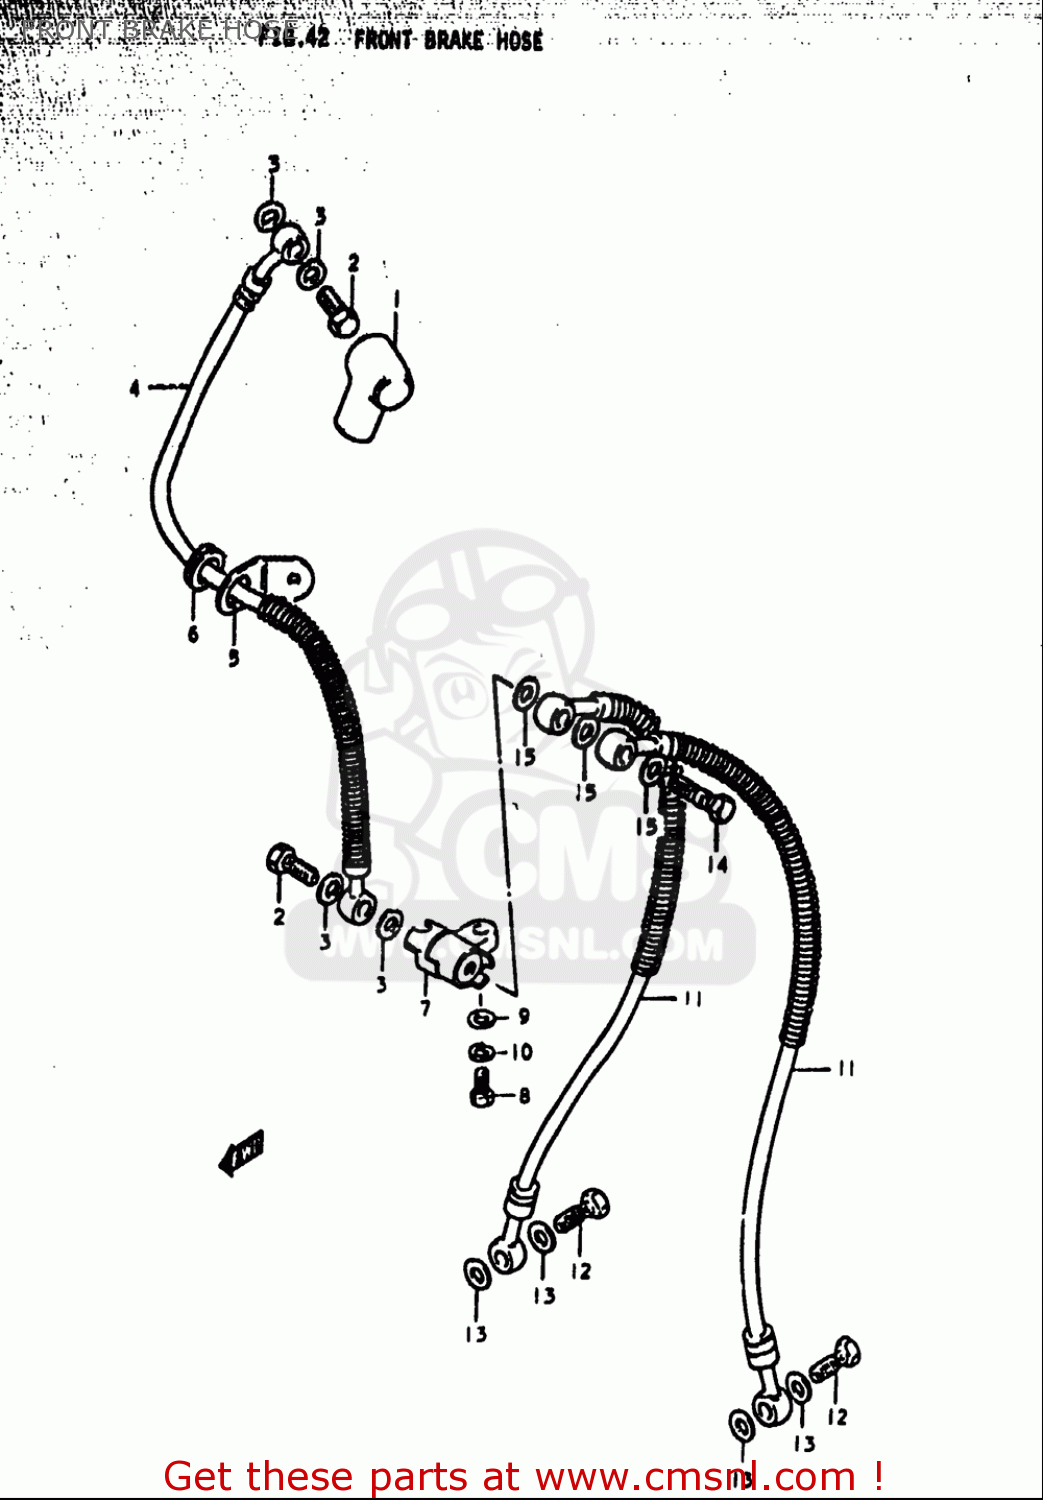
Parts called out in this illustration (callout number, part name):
2	BOLT UNION
3	WASHER(10X15X1.5)
5	GUIDE,BRAKE HOSE
6	GROMMET
7	JOINT,BRAKE HOSE
8	BOLT
9	WASHER
10	WASHER,LOCK
11	HOSE,BRAKE
12	BOLT UNION
13	WASHER(10X15X1.5)
14	BOLT UNION
15	WASHER(10X15X1.5)
